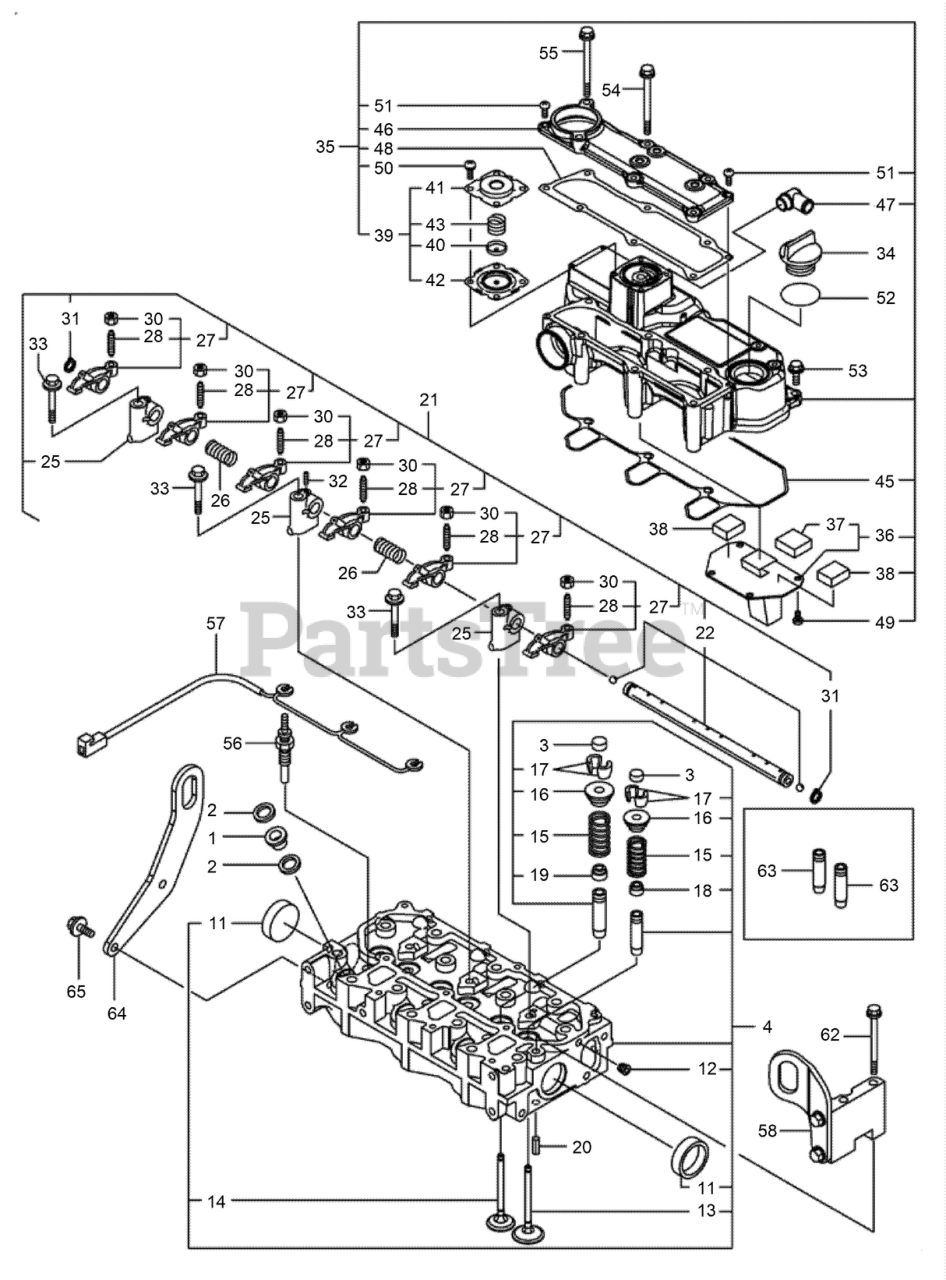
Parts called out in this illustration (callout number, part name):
1	PROTECTOR-NOZZLE
2	GASKET-NOZZLE
3	CAP-VALVE
4	HEAD ASM-CYLINDER
11	PLUG-CUP
13	VALVE-SUCTION
14	VALVE, EXHAUST 3
15	SPRING-VALVE
16	RETAINER
17	COTTER
18	SEAL-STEM, VALVE
19	SEAL-STEM, VALVE
20	PIN-SPRING
21	SUPPORT ASM-ROCKER
22	SHAFT ASM-ROCKER
25	SUPPORT-ROCKER ARM
26	SPRING-ROCKER
27	ARM ASM-ROCKER
28	SCREW-ADJUST, VALVE
34	COVER-FILLER
35	BONNET ASM
36	PLATE-BAFFLE
37	BAFFLE-BREATHER
38	BAFFLE-BREATHER
39	DIAPHRAGM ASM
40	PLATE-DIAPHRAGM
41	COVER-DIAPHRAGM
42	DIAPHRAGM
43	SPRING-DIAPHRAGM
45	GASKET-BONNET
46	COVER ASM-BONNET
48	GASKET
52	O-RING
55	BOLT, M6X 85 PLATED
56	PLUG, GLOW 12V
57	CONNECTOR-PLUG, GLOW
58	LIFTER ASM
64	LIFTER-ENGINE
